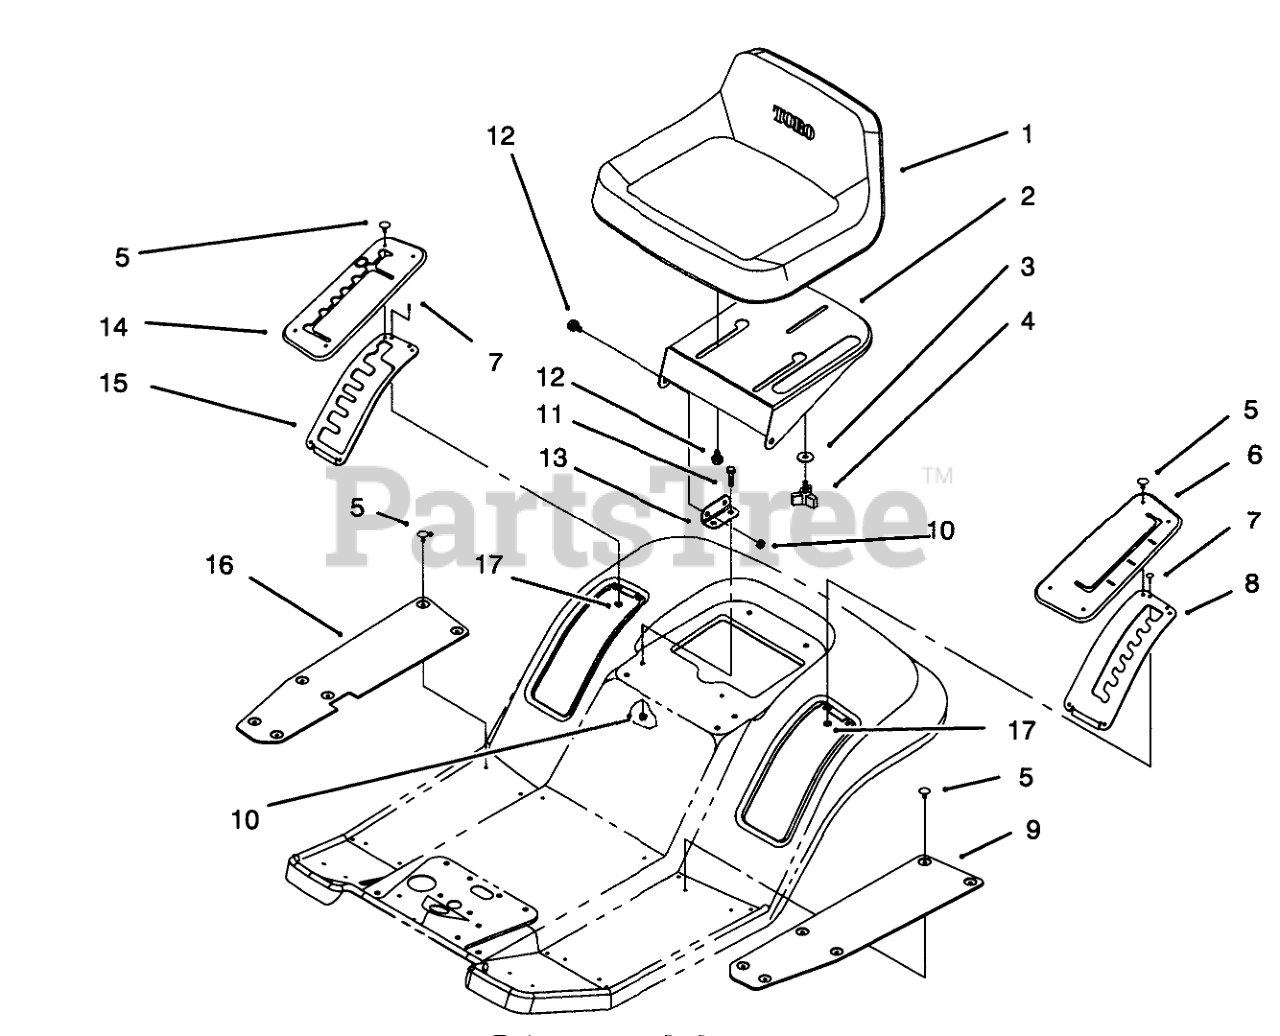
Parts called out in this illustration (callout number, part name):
2	Support-Seat
3	WASHER-PIVOT
5	FASTENER-PANEL
6	COVER-HOC
7	RIVET-POP
8	Gate-H.O.C.
9	MAT-FOOT, LH
10	NUT-LOCK, NI
11	SCREW-HH
12	BOLT-SHOULDER
13	Bracket-Seat Hinge
14	COVER-GATE, SHIFT
15	Gate-Shift
16	MAT-FOOT, RH
17	WASHER-FLAT
